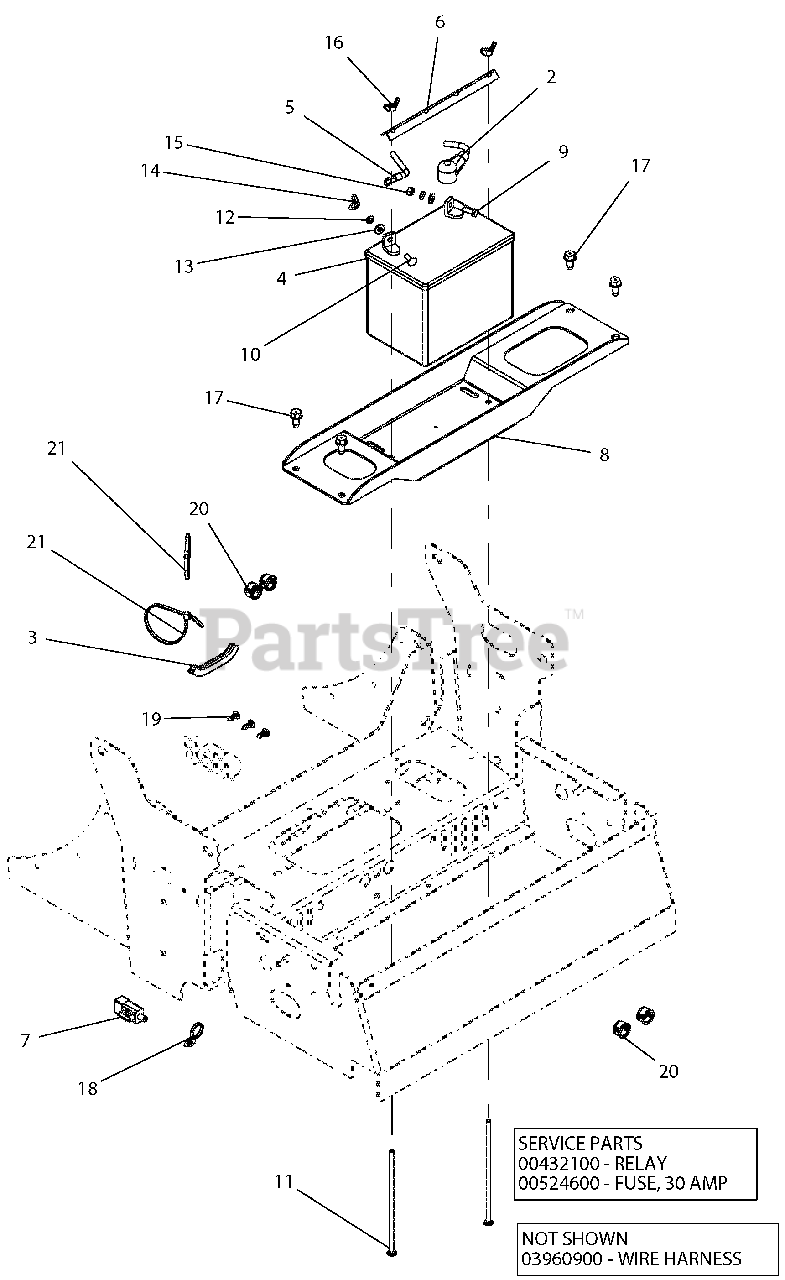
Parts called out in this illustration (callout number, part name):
2	CABLE, POS BATT W/ BOOTS 6 X 35
3	STRIP, COWL - 1.50 LG
4	BATTERY, 300 CCA 10U1L
5	CABLE, NEGATIVE BATTERY 35.00"
6	HOLD DOWN - BLK
7	SWITCH, SNAP IN -N.O./N.O
8	TRAY, BATTERY-RED
9	BLT-HEX .25-20X.75 GR5 YWZC
10	BLT-RDHDSQNK .25-20X.75 G5 YWZC
11	BLT-RDHDSQNK .25-20X7.50 G2 YWZC
12	WSHR-LK .25X.062 REG YWZC
13	WSHR-FL-STL.281X.62X.065 YWZC
14	NUT-WING .250-20 YWZC
15	NUT-HEX .25-20 YWZC
16	NUT-LOCKING WING 1/4-20
17	SCR-TAP .38-16X.75 HWH TR YWZ
18	CABLE TIE W/ TREE (.25 HOLE)
19	RIVET, .25 NYLON PANEL
20	BUSH, PANEL SNAP .687X.875X.56
21	CABLE, TIE 5.50 LG
